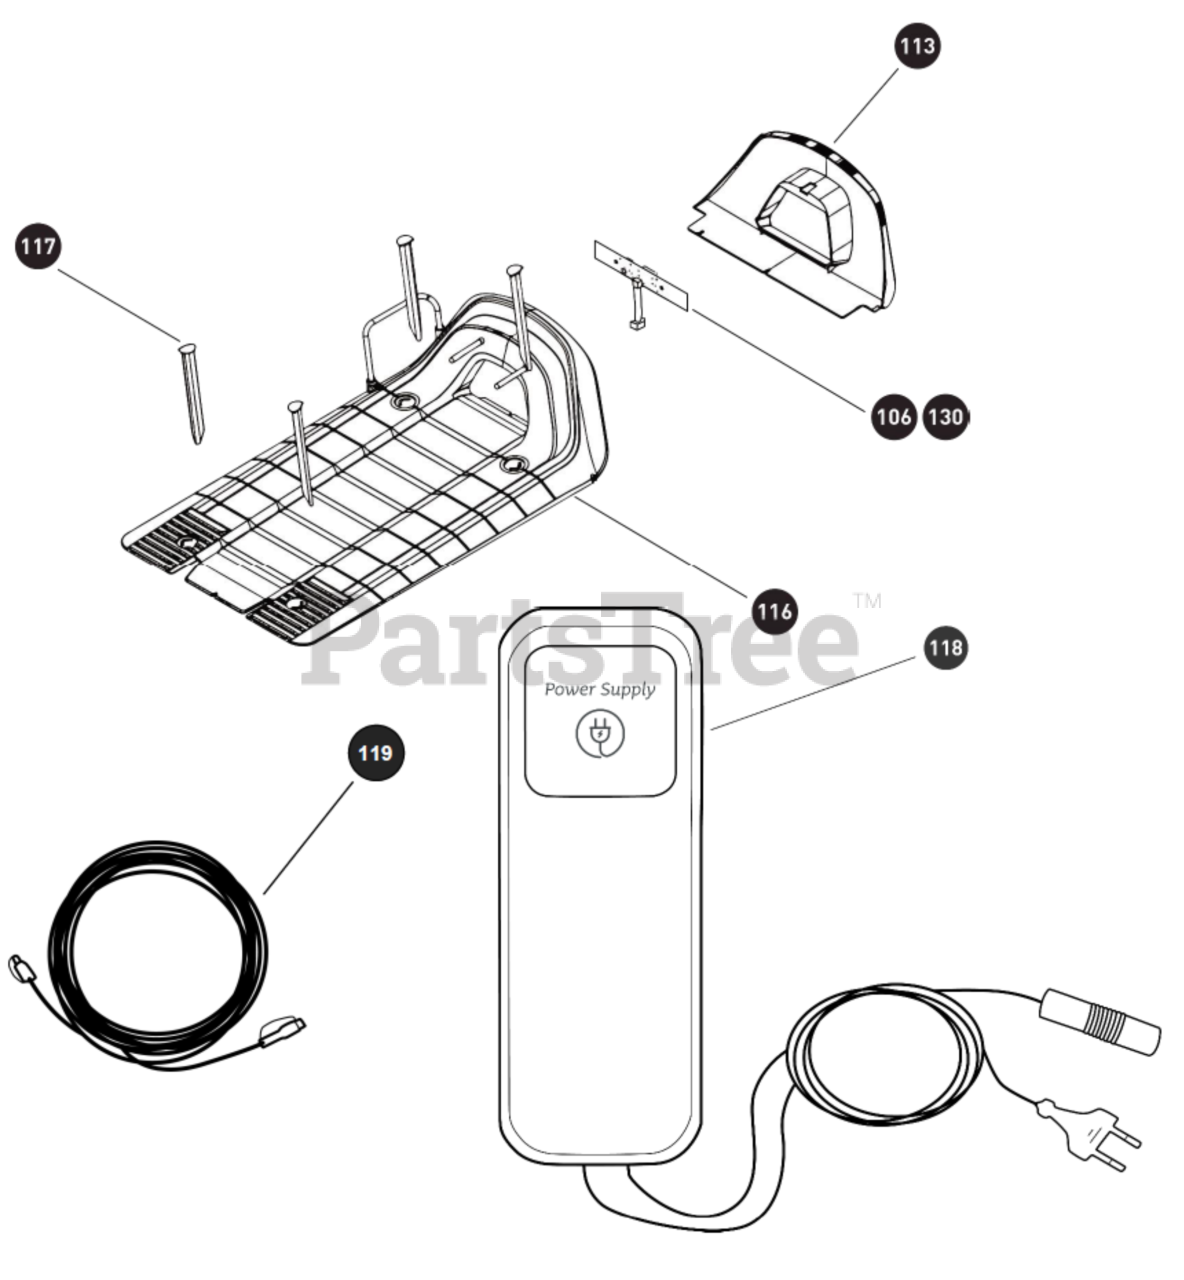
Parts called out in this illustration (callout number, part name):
106	BASE STATION BOARD
113	BASE STATION COVER C
116	BASE STATION W/O ELEC BOARD
117	FASTENING STAKES FOR BASE STATION
118	32V/2A INDOOR SWITCH (IP67)
119	EXTENSION CABLE 15 METERS
